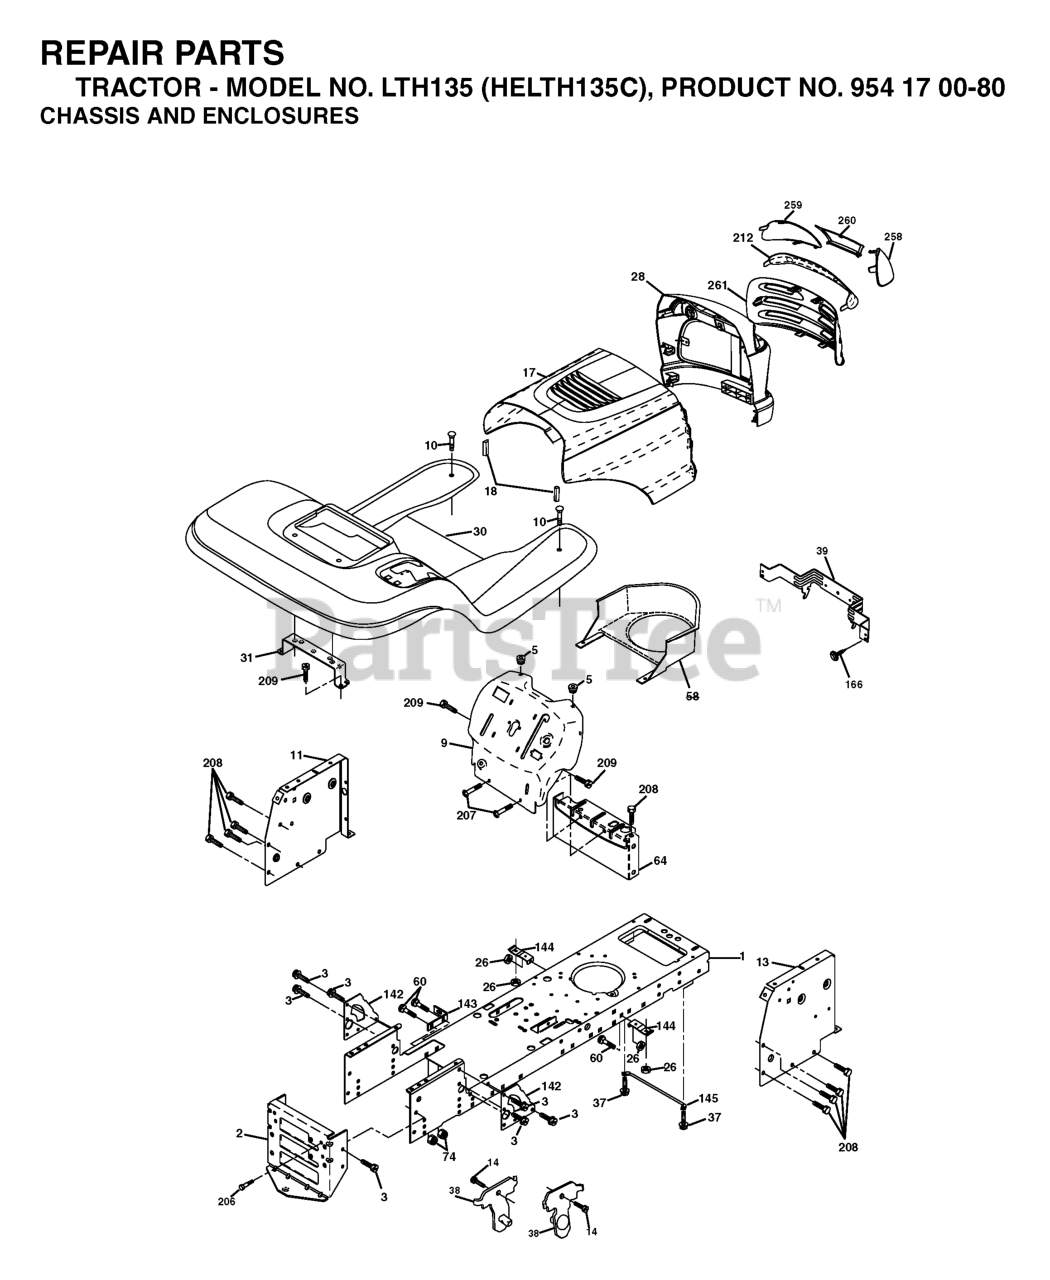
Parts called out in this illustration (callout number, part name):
1	CHASSIS STAMPING
2	DRAWBAR, 12GA
3	SCREW 3/8-16X3/4
5	BUMPER.RUBBER.HOOD
9	DASH
10	BOLT D
11	PANEL.DASH.LH.LTX
13	PANEL DASH RH
17	HOOD
18	BUMPER.HOOD.LARGE.1.75"
26	NUT
30	FENDER FOOTREST
31	BRACKET.SUPPORT.FENDER
37	Screw 5/16-18 x 1/2 Hex, Self Tapping 5/16-18 x 1/2
38	BRACKET.ASM.PIVOT.MOWER.REAR
39	BRACKET PIVOT LASER
58	AIR DUCT P/L/LT
60	Bolt - Rd. Hd. Sq. Neckiage 3/8 16 x 3/4
64	DASH LOWER
142	PLATE REINFORCEMENT
143	BRACKET, SWAY BAR
144	BRKT, FOOT REST
145	ROD PIVOT CHASSIS/HOOD
166	SCREW
206	SHOULDER BOLT 5/16-18TT
207	SCREW, 5/16-18 X 1/2
208	SCREW 3/8-16X1/2
209	SCREW, 3/8-16X3/4
212	INSERT.LENS.REFLECTIVE
258	LENS LH
259	LENS LH
260	COVER.LENS.HUSQ.LASER
